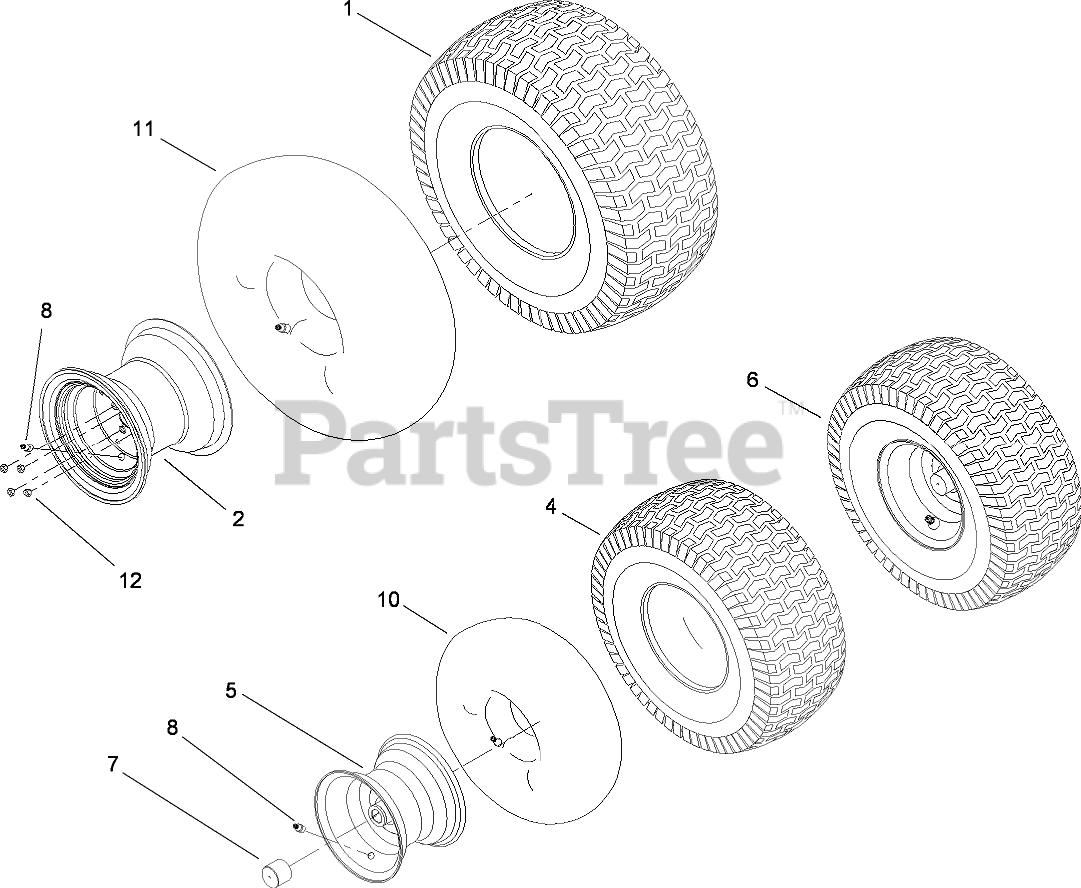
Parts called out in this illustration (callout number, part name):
2	RIM ASM
4	TIRE-TURF
5	Rim-Wheel, Front
6	WHEEL ASM
7	CAP-HUB
8	VALVE-AIR, TUBELESS
10	TUBE-INNER
11	TUBE-INNER
12	NUT-LUG
